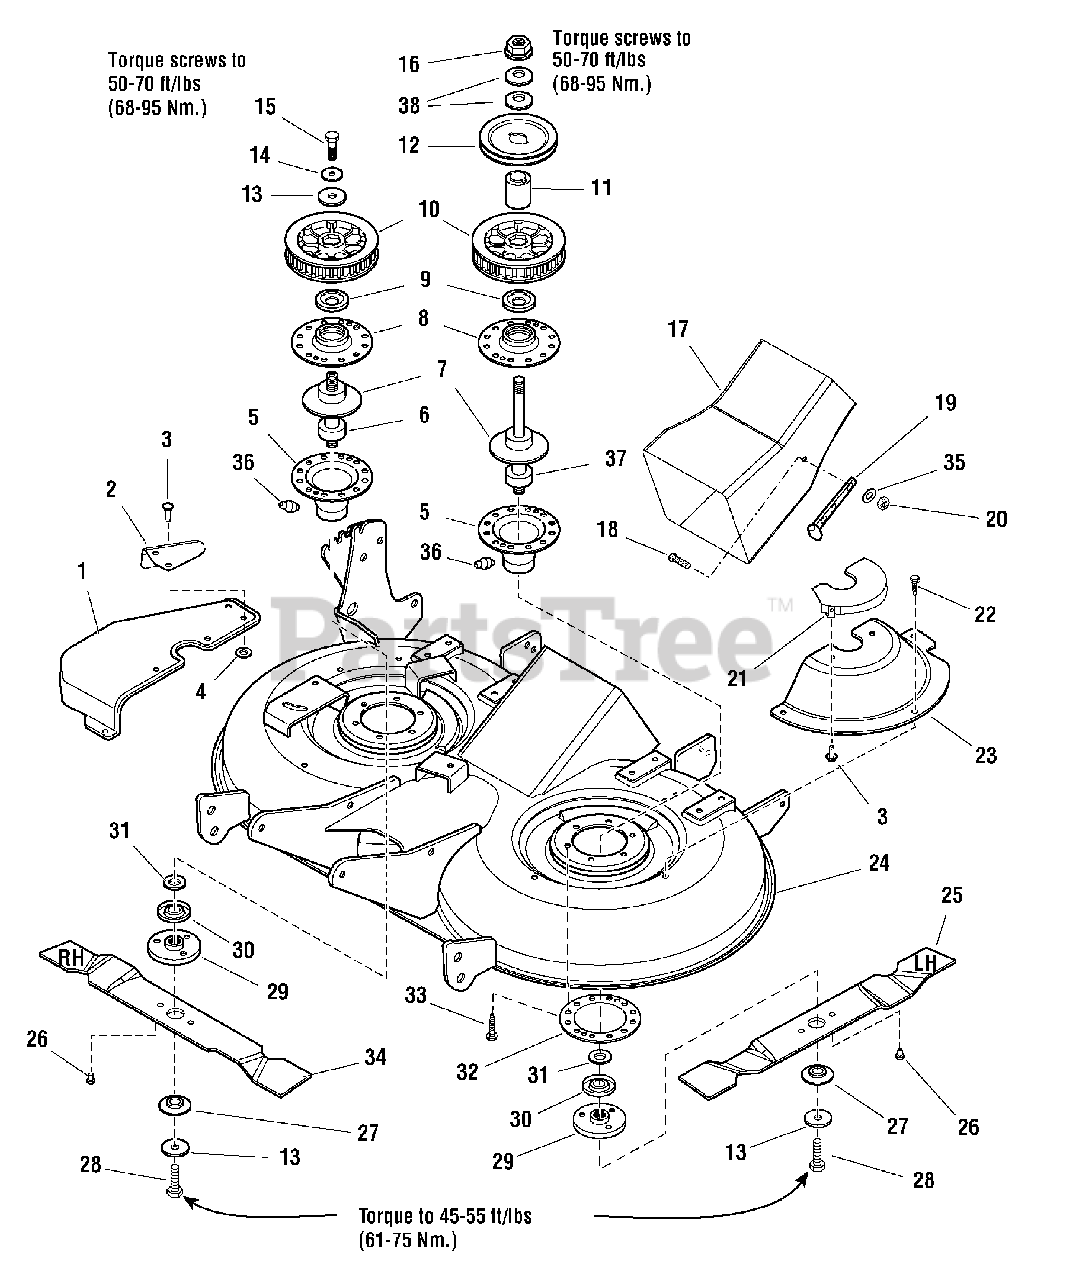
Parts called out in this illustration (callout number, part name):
1	COVER, Arbor, RH
2	GUARD, Extension
3	RIVET, Pop
4	WASHER
5	HOUSING, Arbor, Bottom w/Lube Fitting
6	ARBOR SHAFT & BEARING ASSEMBLY
7	GASKET
8	HOUSING, Arbor, Top
9	SHIELD, Bearing
10	SPROCKET & FLANGE ASSEMBLY, 38 Tooth
11	HUB
12	PULLEY, 5" OD
13	WASHER, Spring
14	WASHER
15	CAPSCREW, Hex Head, 7/16-14 x 2-3/4, GR8
16	NUT, Hex Flange, 9/16-18
17	TUBE CONNECTOR
18	CAPSCREW, Hex Head Phillips, 1/4-20 x 3/4
19	STRAP, Black Rubber
20	NUT, Hex Nylock, 1/4-20
21	GUARD & BRACKET ASSEMBLY, LH
22	CAPSCREW, Hex Head Taptite, 5/16-18 x 3/4
23	COVER, Arbor, LH
24	HOUSING ASSEMBLY
24	HOUSING ASSEMBLY, Red
25	BLADE, Mower, LH
26	PIN, Blade
27	WASHER, Spline
28	CAPSCREW, Hex Head, 7/16-14 x 2-1/4, GR8
29	ADAPTER, Blade
30	SHIELD, Bearing
31	WASHER, Shim
32	ADAPTER, Arbor
33	CAPSCREW, Hex Head Taptite, 5/16-18 x 1
34	BLADE, Mower, RH
35	WASHER, 1/4
36	FITTING, Lube
37	ARBOR SHAFT & BEARING ASSEMBLY
38	WASHER, Bellville, 9/16
